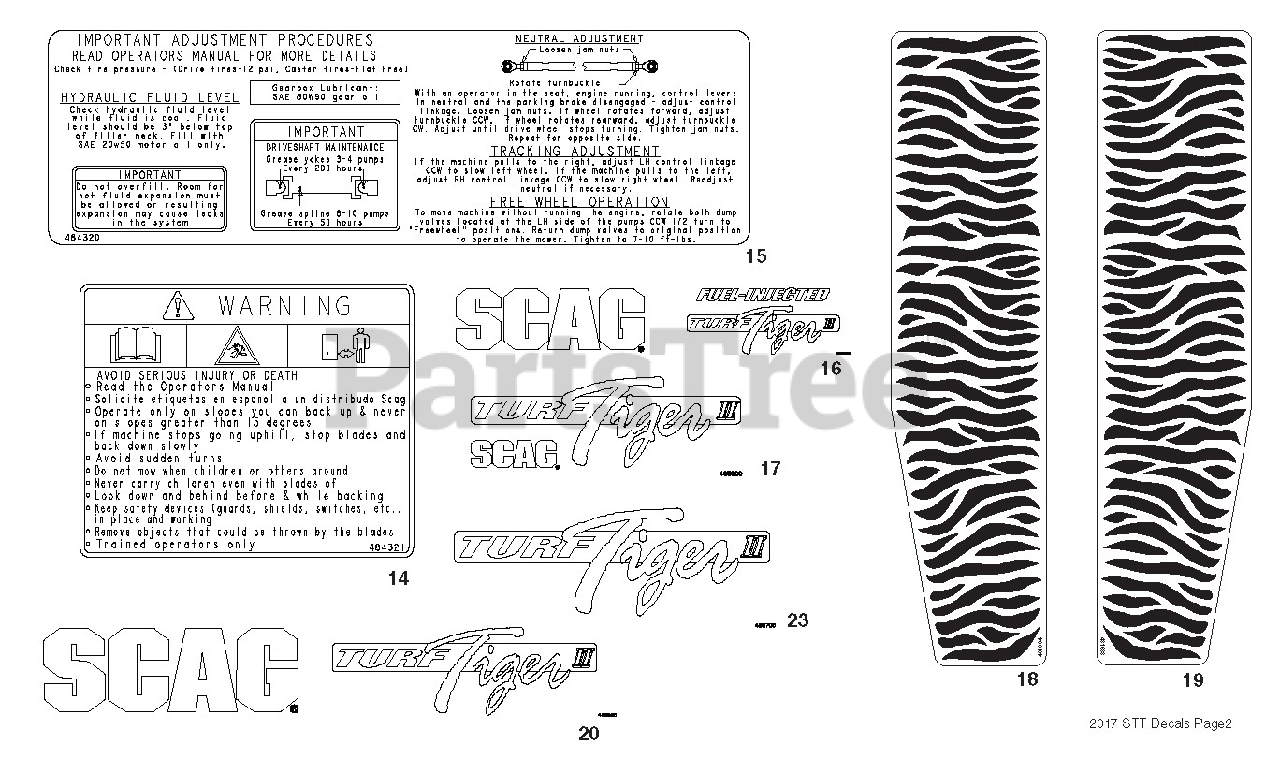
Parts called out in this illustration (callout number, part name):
14	Decal, Fuel Tank Warning
15	Decal, STT Adjustments
16	Decal, Hood - STTII Fuel Injected
17	Decal, Turf Tiger II
18	Decal, Stripes-RH
19	Decal, Stripes-LH
20	Decal, Hood - STTII
23	Decal, Turf Tiger II
